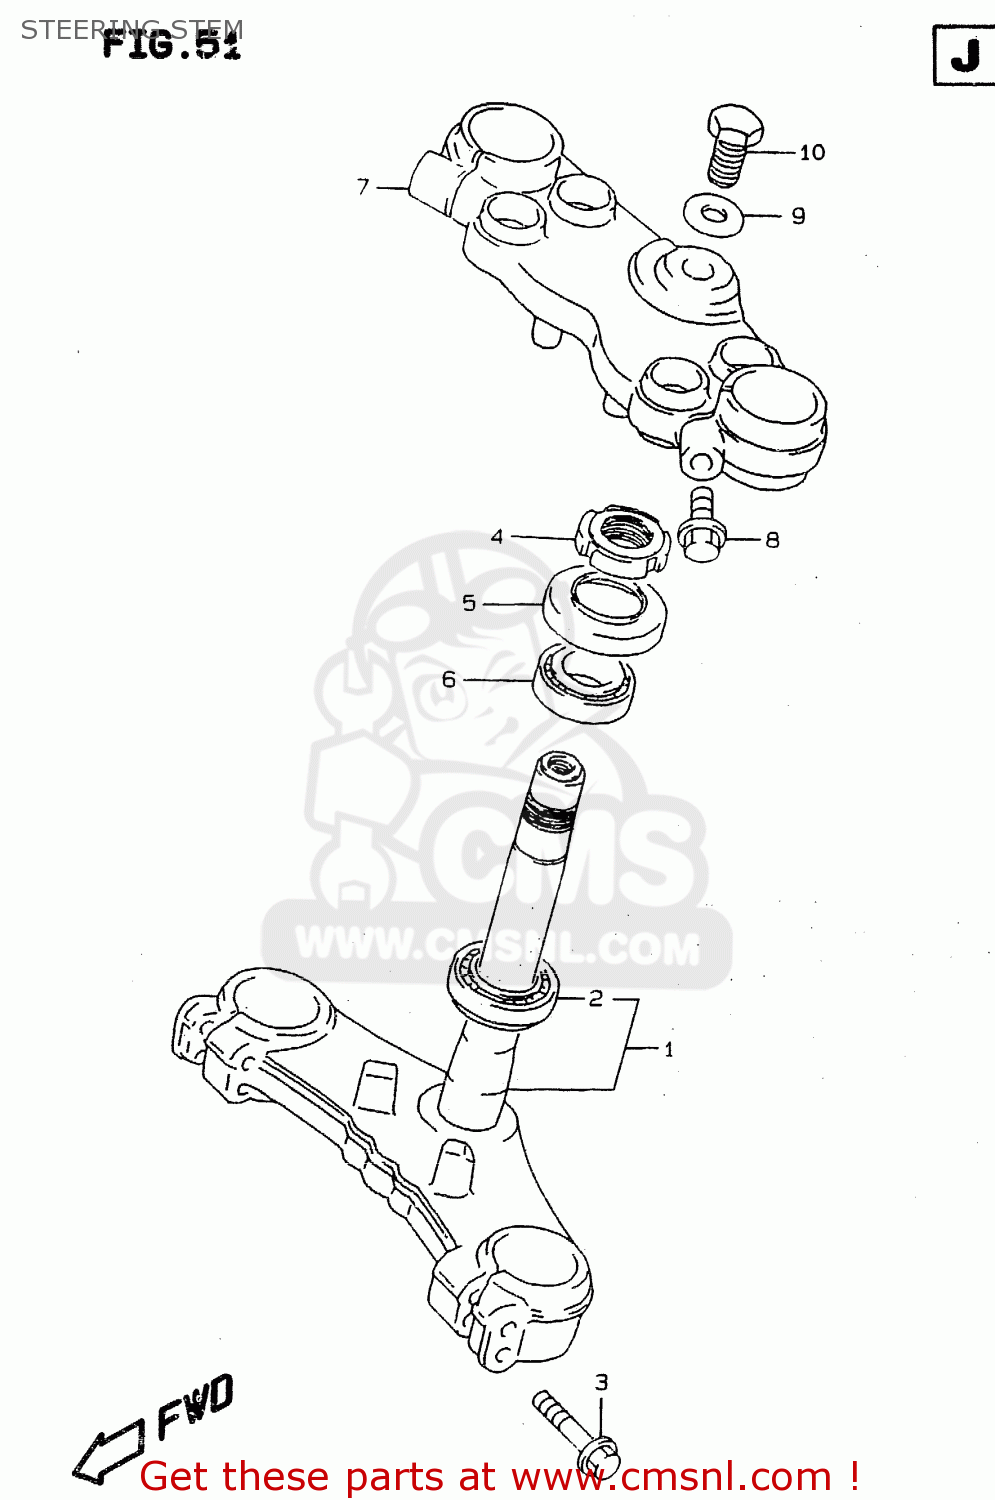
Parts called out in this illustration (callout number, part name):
1	STEM,STEERING
2	BEARING(30X55X17)
3	BOLT
4	NUT,STEERING STEM(25X44X10)
5	SEAL,STEERING UPR DUST
6	BEARING(25X47X15)
7	HEAD,STEERING STEM
8	BOLT
9	WASHER,STEERING STEM
10	BOLT,STEERING STEM HEAD
